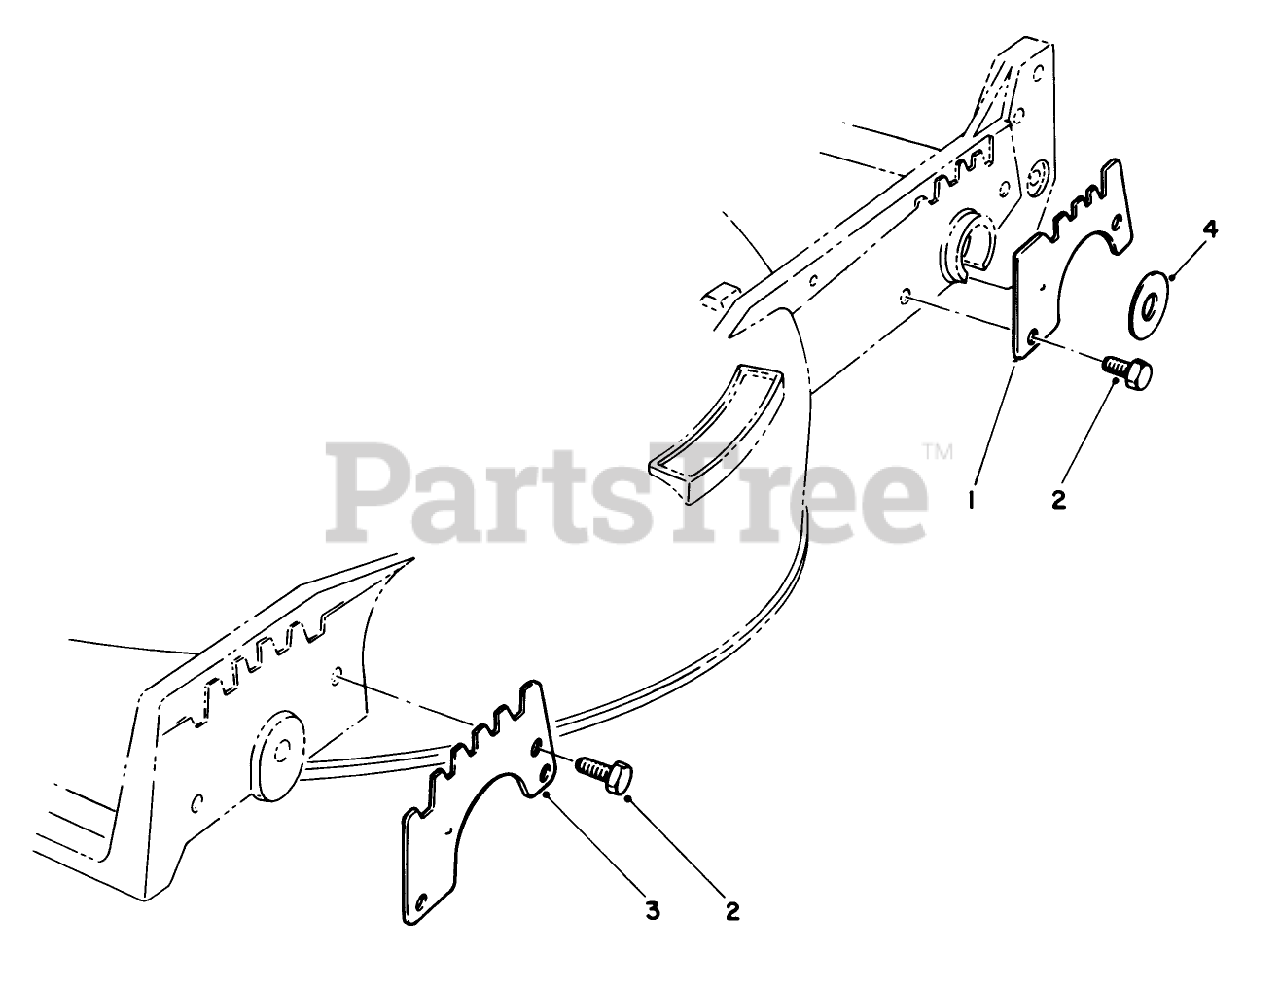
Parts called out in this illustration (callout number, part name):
1	WEAR PLATE,REAR
2	SCREW-HWH
3	WEAR PLATE
4	PIVOT WASHER
